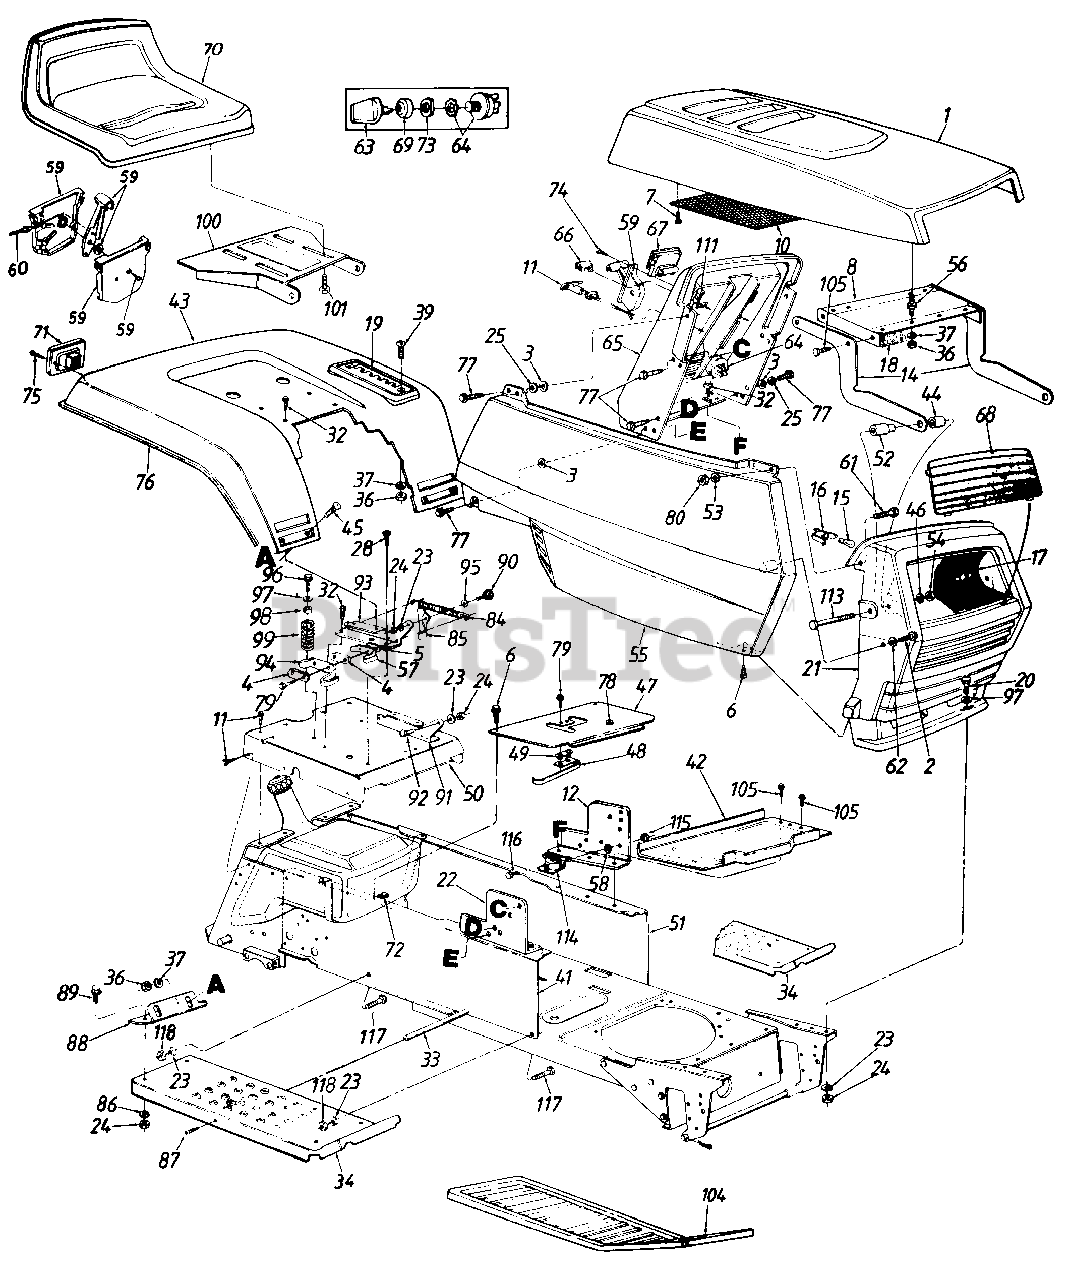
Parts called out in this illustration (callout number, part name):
3	Bolt Retainer 1/4" I.D.
4	Insulator Plate
5	Insulator Boss Plate
6	Truss Mach. B-Tap Scr. #10 x .5" Lg.
7	Hex Wash Hd. AB-Tap Scr. #8 x .5" Lg.
8	Hood Plate
11	Choke Control
12	Dash Support Brkt.-L.H.
14	Hood Hinge
15	Lamp
16	Twist Lock-Lamp Socket
17	Reflector-Headlight
19	Speed Control Index Brkt.
20	Hex Bolt 5/16-18 x .75" Lg.
21	Grille
22	Dash Support Bracket-R.H.
23	L-Wash. 5/16" I.D.
24	Hex Nut 5/16-18 Thd.
25	Fl-Wash. 1/4" I.D. x .93" O.D.
32	Hex Wash. Hd. AB-Tap Scr. 5/16 x .75" Lg.
33	Running Board Rod
37	L-Wash. 1/4" l.D.
39	Truss Mach. Scr. 1/4-20 x .62"
41	R.H. Side Frame
42	Support Brkt.
45	Carriage Bolt 1/4-20 x .50" Lg.
46	Fl-Wash. .328" I.D. x .68" O.D.
47	Transmission Panel
48	Reverse Safety Switch
49	Insulator Nut Plate
50	Seat Plate
53	Fl-Wash. .281" I.D. x ,5n O.D.
54	Hex Cent. L-Nut 5/16-18 Thd.
55	Side Cover-R.H.
56	Double Ended Stud 1/4-20 Thd.
57	Safety Switch
58	Ext. L-Wash. 114" I.D.
59	Throttle Control Box Ass'y.
60	Throttle Control Wire 35" Lg.
61	Hex Bolt 1/4-20 x .62" Lg.
62	Fl-Wash. .281" I.D. x .73" O.D.
64	Ignition Switch
66	Light Switch
67	Ammeter
68	Lens
69	Ignition Switch Cap
71	Taillight Ass'y.
72	Speed Nut #10Z
73	Ignition Switch Nut
74	Truss Mach. AB-Tap Scr. #10 x .5" Lg.
75	Truss Hd. AB-Tap Scr. #6 x .62" Lg.
76	Trim Strip-81n
77	Hex Wash. Hd. Tap Scr. 1/4 x .75n Lg.
78	Snap Bushing
79	Hex Wash. Hd. AB-Tap Scr. #8 x .50n Lg.
80	Hex L-Nut 1/4-20 Thd.
84	Ext. Spring 5.31" Lg.
85	Seat Lift Brkt.
86	Bell-Wash. .345" l.D. x .88" O.D.
87	Rib Neck Bolt 5/16-18 x .75"
90	Shld. Bolt .437n Dia. x .268"
95	Spr.-Wash. .445" I.D.
96	Hex Wash. Hd. Tap Scr. 5/16-18 x 1" Lg.
97	Fl-Wash. .344" I.D.
99	Compression Spring
100	Seat Pivot Bracket
101	Hex Tap Scr. 3/8-16 x .75"
105	Hex Tap Scr. 1/4-20 x .5" Lg.
111	Speed Nut 1/4-20 Thd.
113	Hex Bolt 5/16-18 x 2.75"
114	Solenoid
115	Hex Sems Nut 1/4-20 Thd.
116	Hex Bolt 1/4-20 x .5n Lg.
117	Rib Neck Bolt 5/16-24 x .75n Lg.
118	Hex Nut 5/16-24 Thd.
